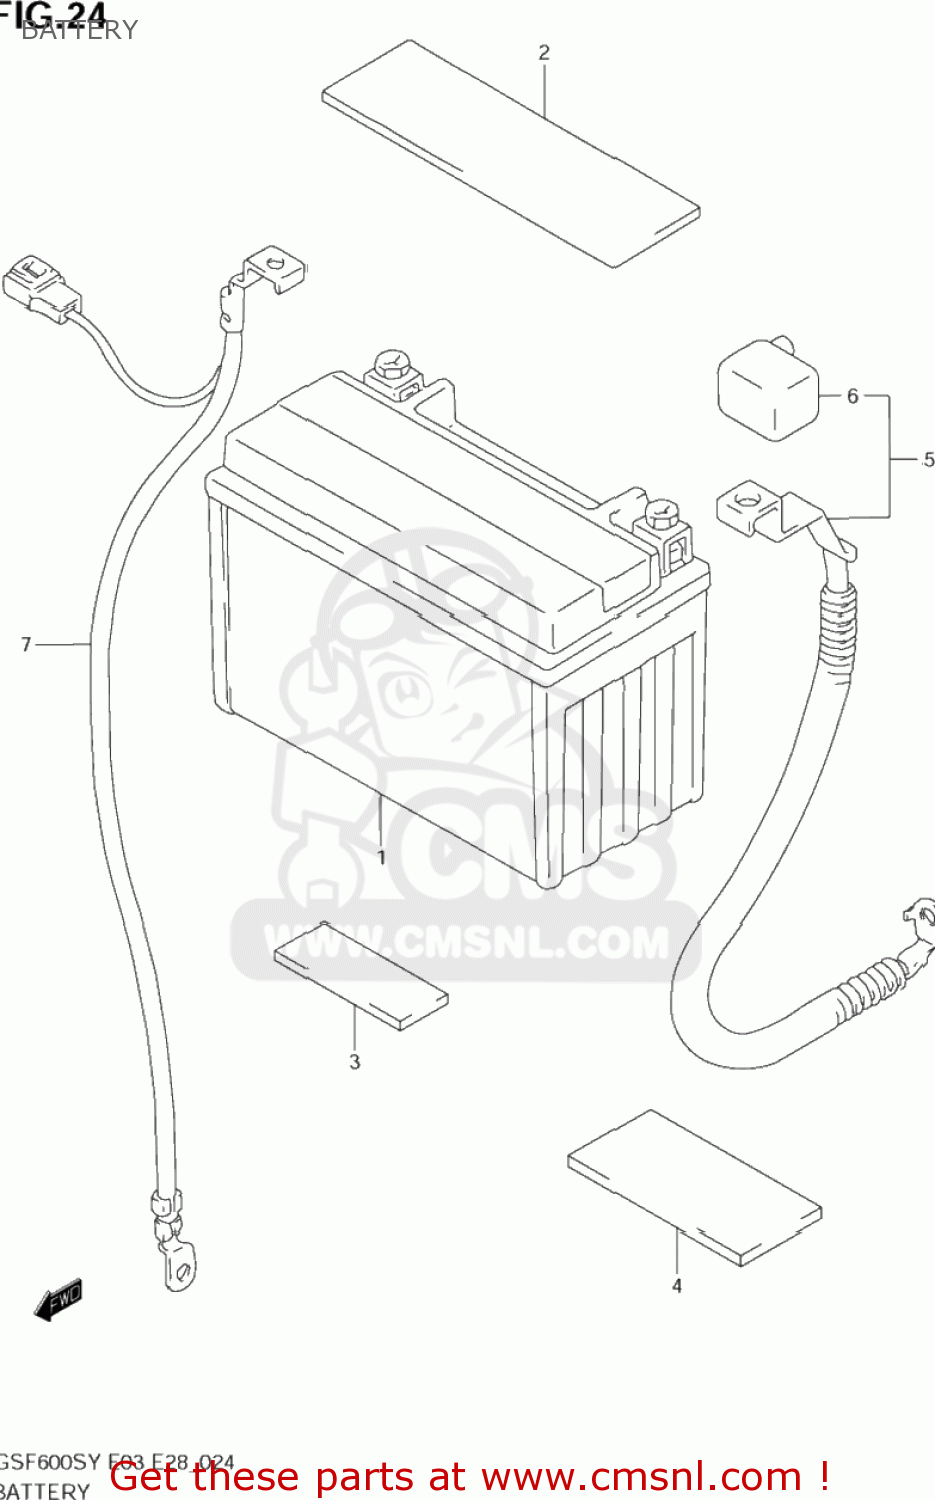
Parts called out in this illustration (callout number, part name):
1	BATTERY ASSY(YTX9-BS,12V8AH)
2	PROTECTOR(170X95X3.0)
3	PROTECTOR(20X50X11)
4	CUSHION,BATTERY
5	WIRE,BATTERY PLUS LEAD
6	CAP,BATTERY PLUS
7	WIRE,BATTERY MINUS LEAD
